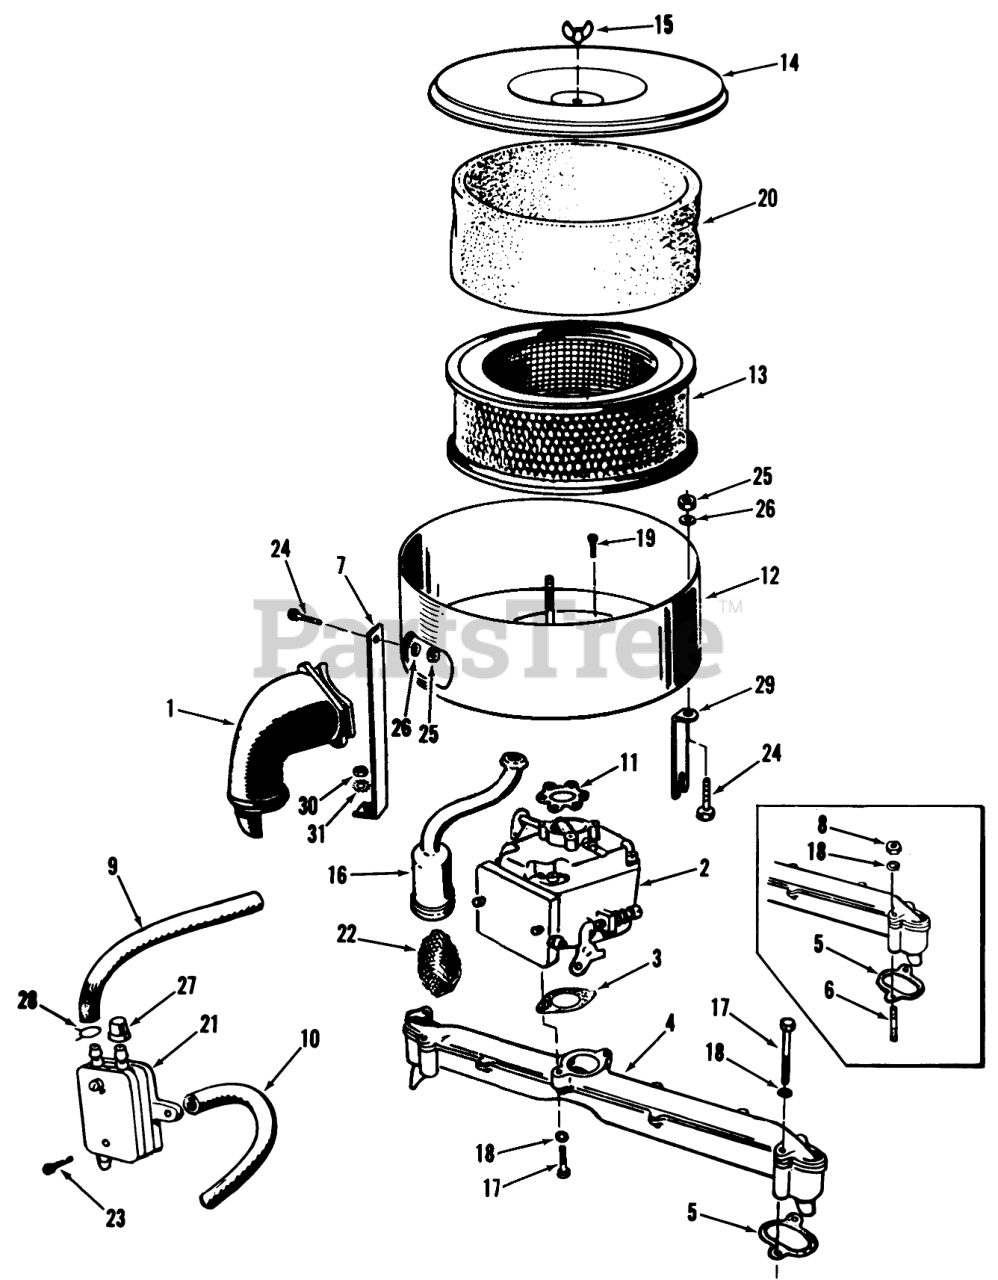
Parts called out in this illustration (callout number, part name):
3	Carburetor Mounting Gasket
13	ELEMENT-AIR CLEANER
19	SCREW-RD HD10-32X3/8
21	Fuel Pump
